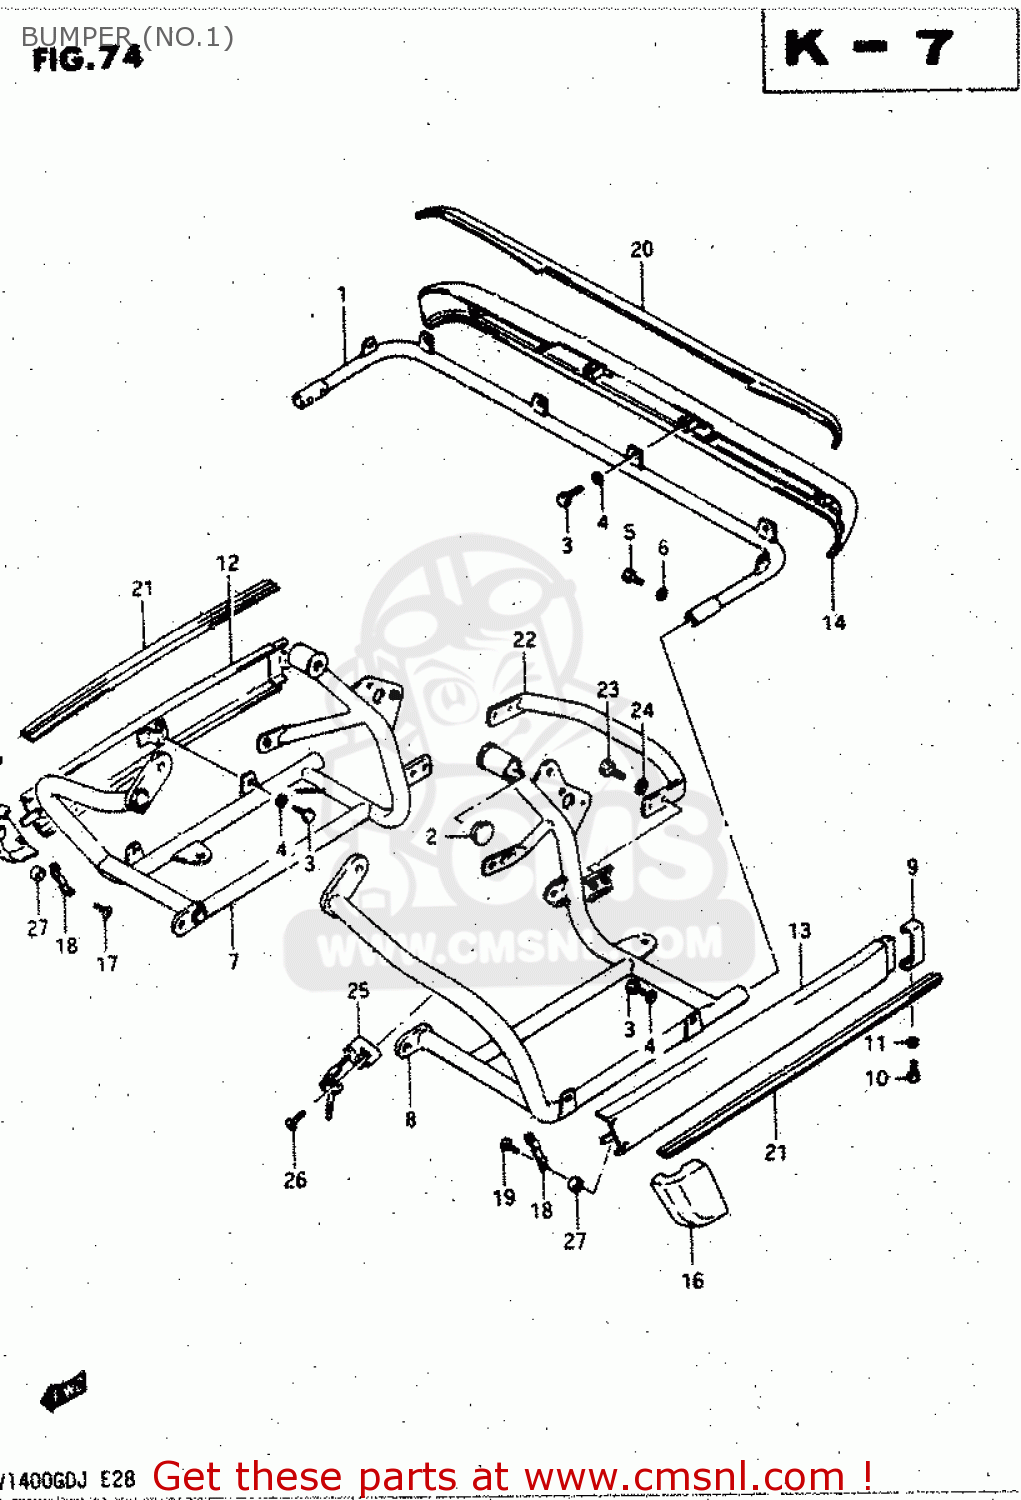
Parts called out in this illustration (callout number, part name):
1	BUMPER,REAR,CENTER
2	CAP,FRAME HANDLE GRIP
3	BOLT
4	WASHER,LOCK
5	BOLT
6	WASHER,LOCK
7	BUMPER,REAR SIDE,RIGHT
8	BUMPER,REAR SIDE,LEFT
9	PLATE,SIDE BAG CARRIER,CTR
10	BOLT
11	WASHER,LOCK,10
12	TRIM,SIDE BAG CARRIER
13	TRIM,SIDE BAG CARRIER
14	TRIM,SIDE BAG CARRIER
15	COVER,SIDE BAG CARRIER
16	COVER,SIDE BAG CARRIER
17	SCREW
18	BRACKET,SIDE BAG CARRIER
19	SCREW
20	CUSHION,SIDE BAG RL
21	CUSHION,SIDE BAG TRIM
22	PIPE COMP,REINFORCING SIDE B
23	BOLT
24	LOCK WASHER
25	LOCK SET,TOOL HOLDER
26	SCREW
27	SPACER (6.6X9X6.5)
